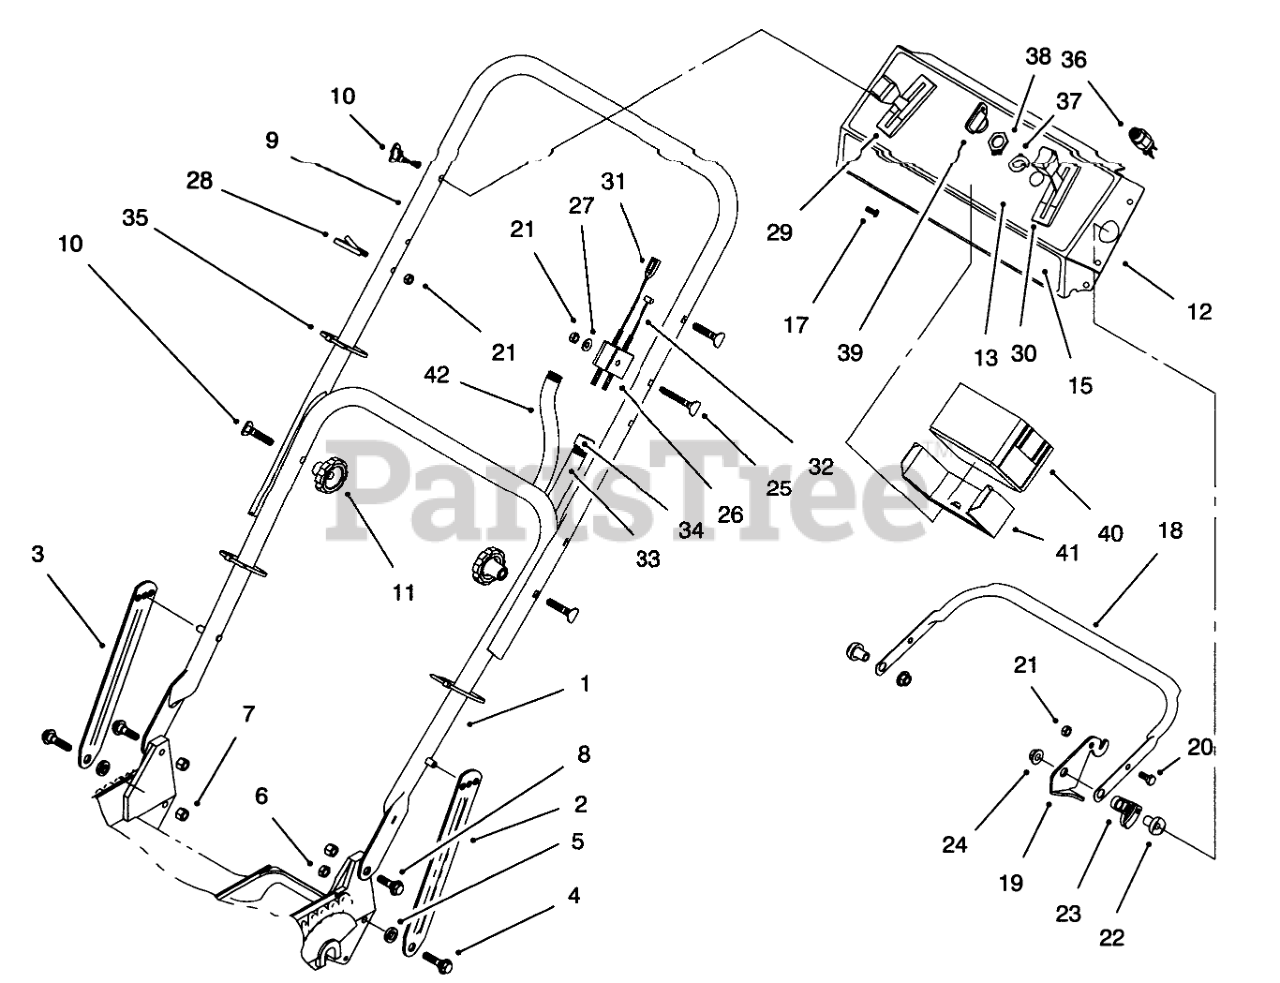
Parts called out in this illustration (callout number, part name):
1	ASM-Handle
2	Latch-Handle
3	Latch-Handle
4	SCREW-SHOULDER
5	SPACER
6	NUT-LOCK, NI
7	NUT-LOCK, NI
8	SCREW-SHOULDER
9	Handle-Upper
10	SCREW-HANDLE
12	Panel-Control (Incl. Ref. #13)
13	DECAL - CONSOLE
15	DECAL - CONSOLE
17	SCREW-TAP
18	Bar-Control
19	Lever-Control
20	SCREW-HH
21	NUT-LOCK, NI
22	SPACER-SUPPORT
23	LEVER-TRACTION
24	NUT-LOCK NI
25	SCREW-HANDLE
26	SUPPORT-CABLE
27	WASHER-FLAT
28	GUIDE-ROPE
29	CONTROL-SPEED, GROUND
30	CABLE - THROTTLE
31	CABLE - BRAKE
32	CABLE-TRACTION
33	CONTROL CABLE COVER
34	FITTING-RING
35	TIE-CABLE
36	Switch-Starter (Incl. Ref. #37 & 38)
37	WASHER-TOOTH, INTERNAL
38	NUT-HH
39	KEY-IGNITION
40	BATTERY ASSEMBLY
41	Retainer-Battery
42	WIRING HARNESS
